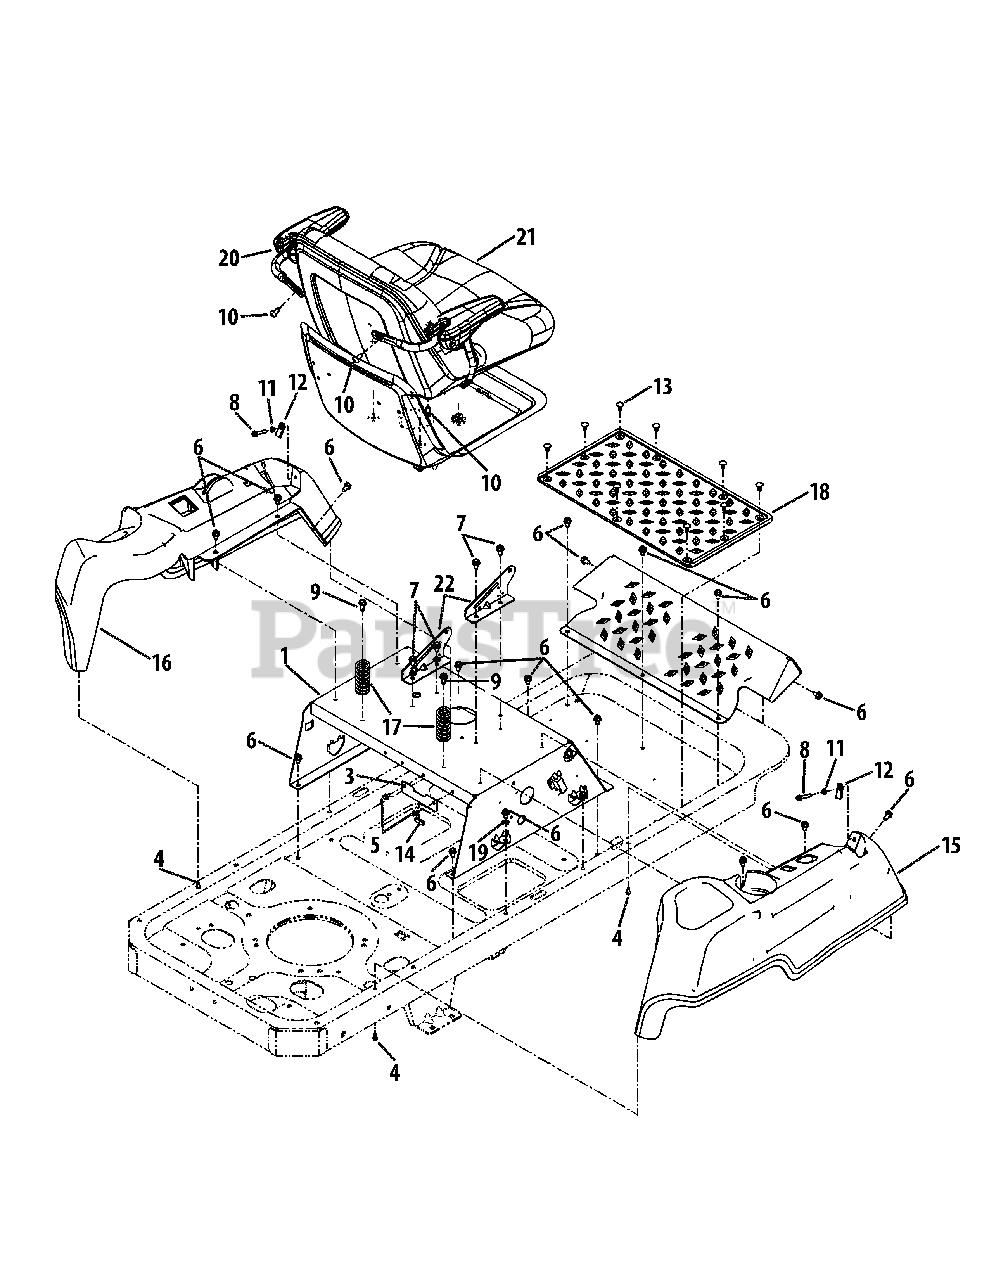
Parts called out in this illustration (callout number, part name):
4	Hex Washer Hd. Screw, #12-16 x .50
5	Hex Washer Hd. Screw, 1/4-20 x .500
6	Hex Washer Hd. Screw, 5/16-18 x .625
7	Hex Washer Hd. Screw, 5/16-12 x .750
8	Hex Wshr. Hd. Screw, 1/4-20 x 1.500
9	Hex Wshr. Hd. Screw, 5/16-18 x .750
10	Hex Screw, 5/16-18 x .750
11	Jam Nut, 1/4-20
12	Speed Nut, 1/4-20
13	Ratchet Clip, .250
14	Trim Strip
15	Console (RH) Oyster Gray
15	Console (RH) Black
16	Console (LH) Oyster Gray
16	Console (LH) Black
17	Compression Spring, 1.28 x 3.125
18	Foot Pad
19	External Tooth Lock Washer, 3/8
20	Arm Rest Kit
21	High Back Seat, Gray
21	High Back Seat, Black
